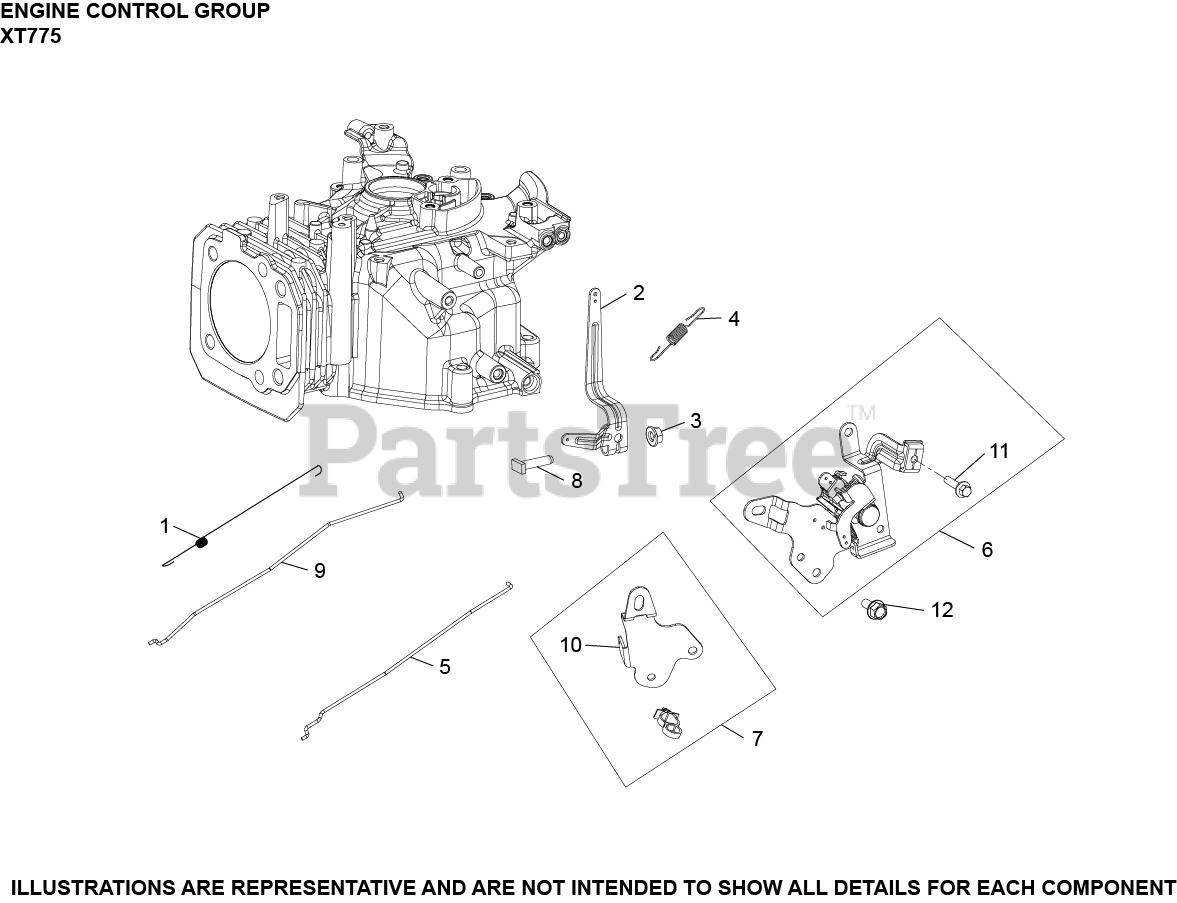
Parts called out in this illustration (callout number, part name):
1	SPRING, LINKAGE
2	LEVER, GOVERNOR
3	NUT, HEX FLANGE (M6)
4	SPRING, GOV (2800-3300 RPM)
8	SCREW, HEX FLANGE (M6) (CKY)
9	LINKAGE, GOVERNOR
